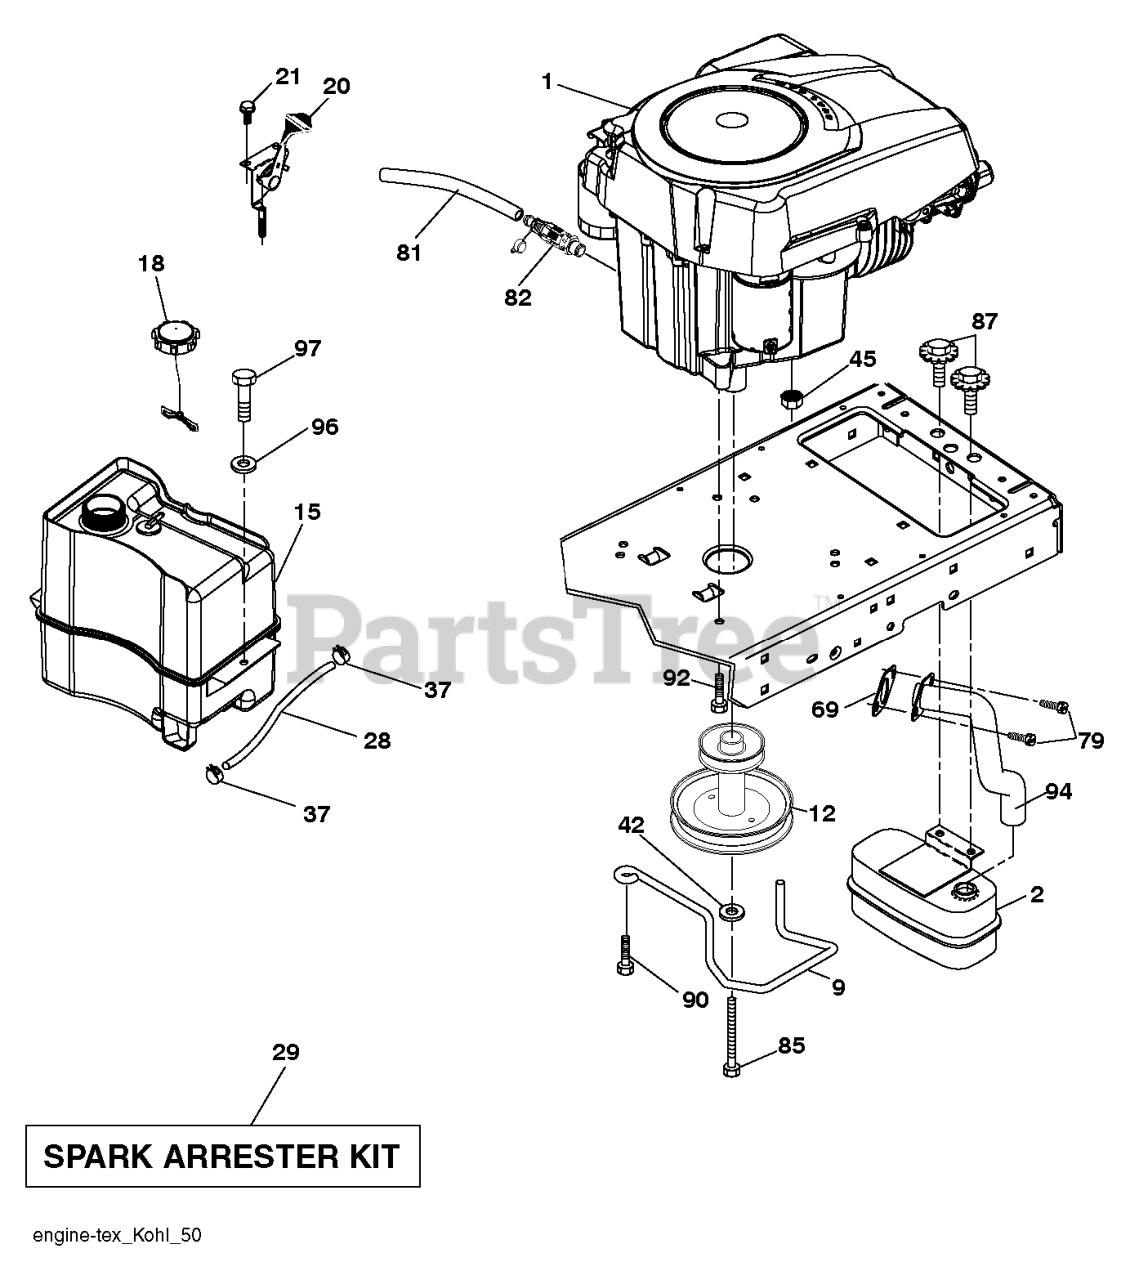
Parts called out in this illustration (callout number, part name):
2	MUFFLER.SINGLE.LRG.BRIGGS.KOHL
9	KEEPER.BELT.ENGINE
12	PULLEY.ENGINE
15	FUEL.TANK.ASM.NON-EPA
18	FUEL CAP
20	CONTROL.TH/CK.C.
21	SCREW.#10 X 0.750.BOS
28	LINE.FUEL.20
29	KIT.SPARK ARRESTOR 794945 B&S
37	HOSE CLAMP
42	LOCKWASHER
45	NUT
69	GASKET.EXHAUST.KOHLER
79	SCREW.SOCKET HD.5/16-1
81	TUBE, DRAIN OIL ASM.
82	VALUE.OIL.DRAIN
85	BOLT HEX 7/16-20X4-1/4"
87	BOLT.5/16-18UNCX3/4 W/SEMS.BLK
90	SCREW 3/8-16X1
92	SCREW 3/8-16X1
94	TUBE.EXHAUST.KOHLER.COURAGE
97	SCREW HEXWSHR 1/4-20X3/4
